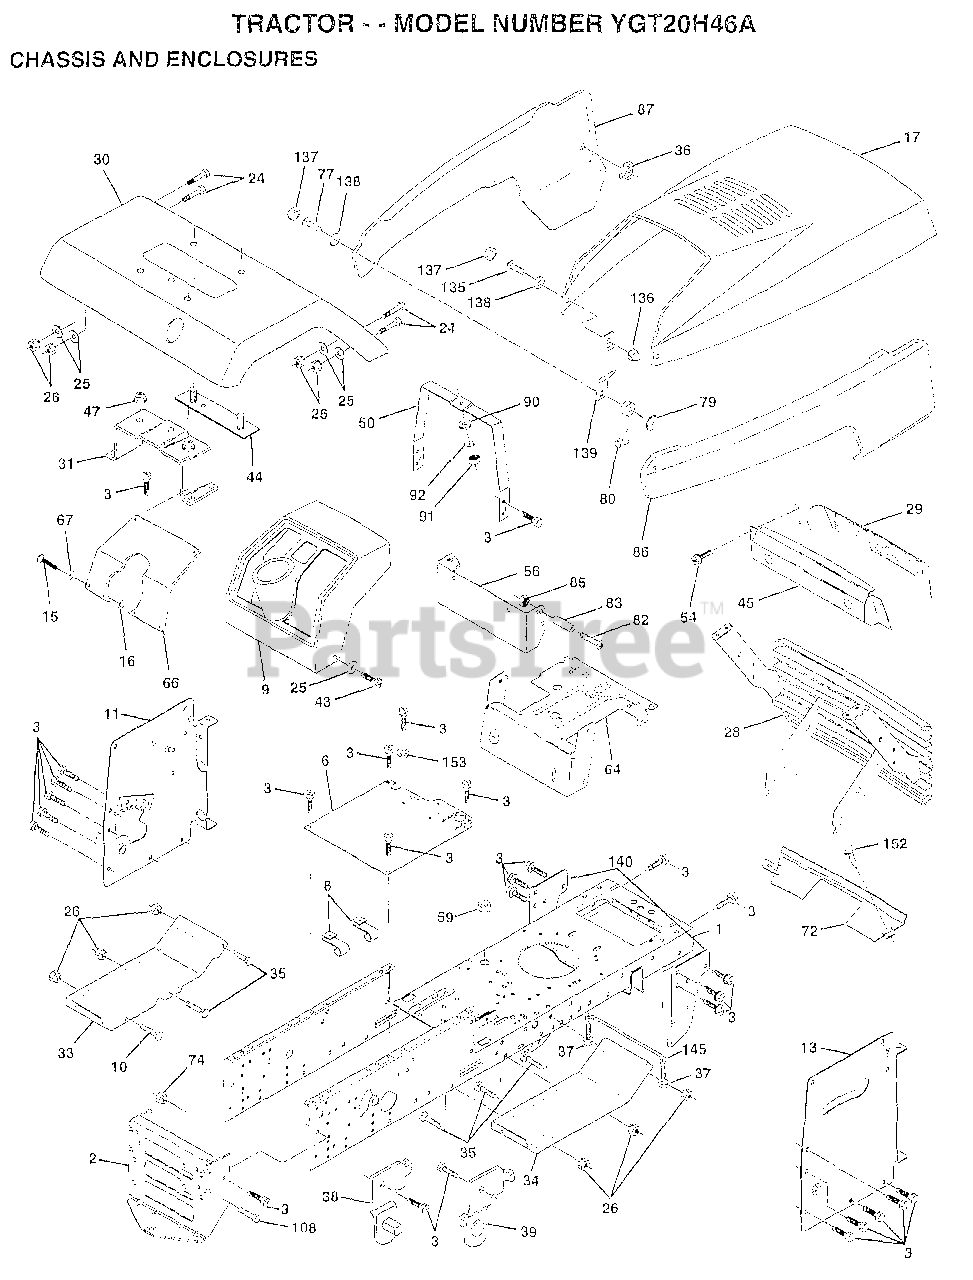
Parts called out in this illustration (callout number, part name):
1	CHASSIS.STAMPING
3	SCREW
6	SADDLE
8	"CLIP,INSULATOR"
9	DASHBOARD BLACK
11	DASHBRD.PANEL.LH
13	DASHBRD.PANEL.RH
15	SCREW
17	"HOOD, YARD PRO"
24	BOLT
25	WASHER
26	NUT
28	GRILLE ASM PNT
29	LENS.BAR.CLEAR
30	"FENDER WS,FTK"
31	BRKT.ASM.FENDER
33	FOOTREST PNT LH
34	FOOTREST.RH.LT/GT
35	BOLT
36	PAL NUT LT
37	SCREW LT
38	BRACKET ASM LH
39	BRACKET ASM RH
43	SCREW
44	STRAP ASM FENDER
45	BEZEL.ASM.
47	NUT-PUSH YT
50	DASH.SUPT.YP/HUSQ
54	SCREW.HEX.WS.HD
56	EXT DASH LTYT
64	DASH.LOWER.LT
67	WASHER
77	SCREW
79	WELDNUT
80	HOOD LATCH T
82	SCREW
83	SPACER LT
86	"PANEL ASM SIDE,RH"
87	"PANEL ASM-SIDE,LH"
90	WASHER PM
92	LOCKWASHER
135	SCREW.10-24X3/8.
136	ACORN NUT RB
137	SNAP CAP LT
138	WASHER LT
139	BKT.SPT.HOOD/PANL
140	BRKT SUSPENSION
145	"ROD POVOT,CHASSIS"
152	SCREW
153	WASHER GT
